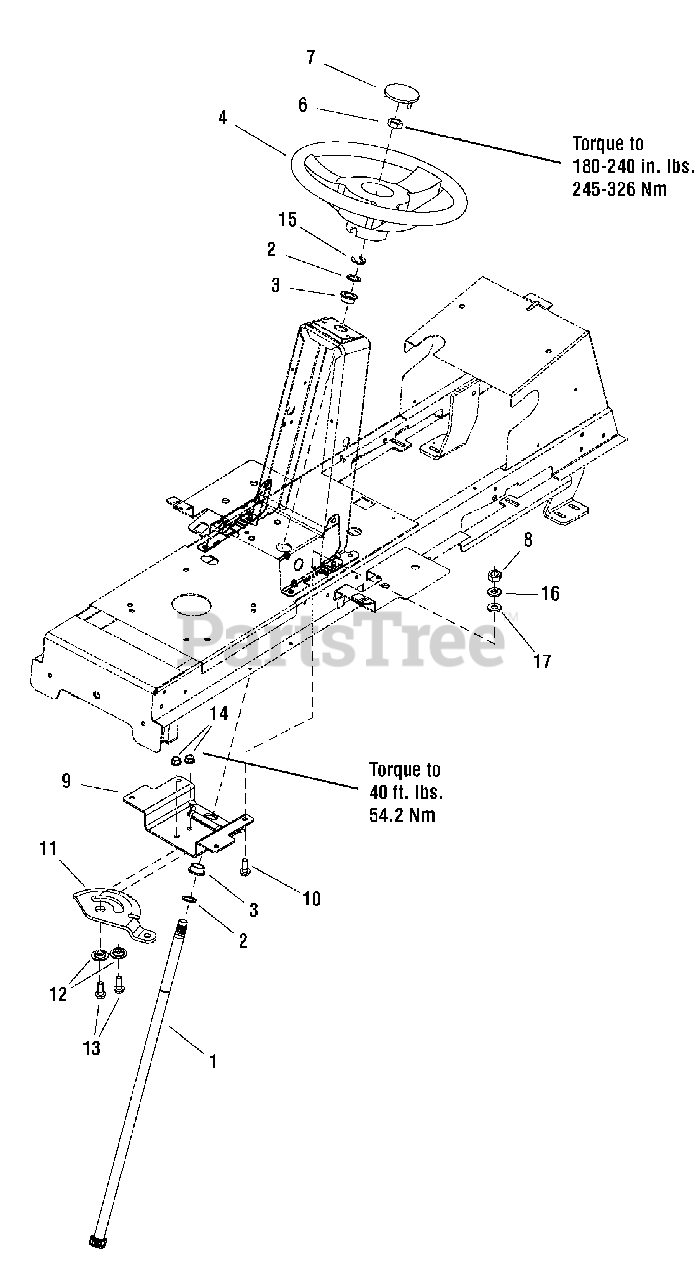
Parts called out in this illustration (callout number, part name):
1	SHAFT, Steering Gear & Spline
2	WASHER, 3/4
3	BUSHING
4	STEERING WHEEL
6	NUT, Hex Lock 5/8-18
7	CAP, Steering Wheel, Snapper
8	NUT, M8
9	BRACKET, Sector Support
10	BOLT, M8 x 25
11	GEAR, Steering , 1/4 Thick, 26 teeth
12	SPACER, Sector Gear
13	SCREW, Hex Lock Flange, 3/8-16 x 1
14	NUT, Hex Flange, 3/8-16
15	RING, Klipring
16	WASHER, 8.4
17	WASHER, 8
